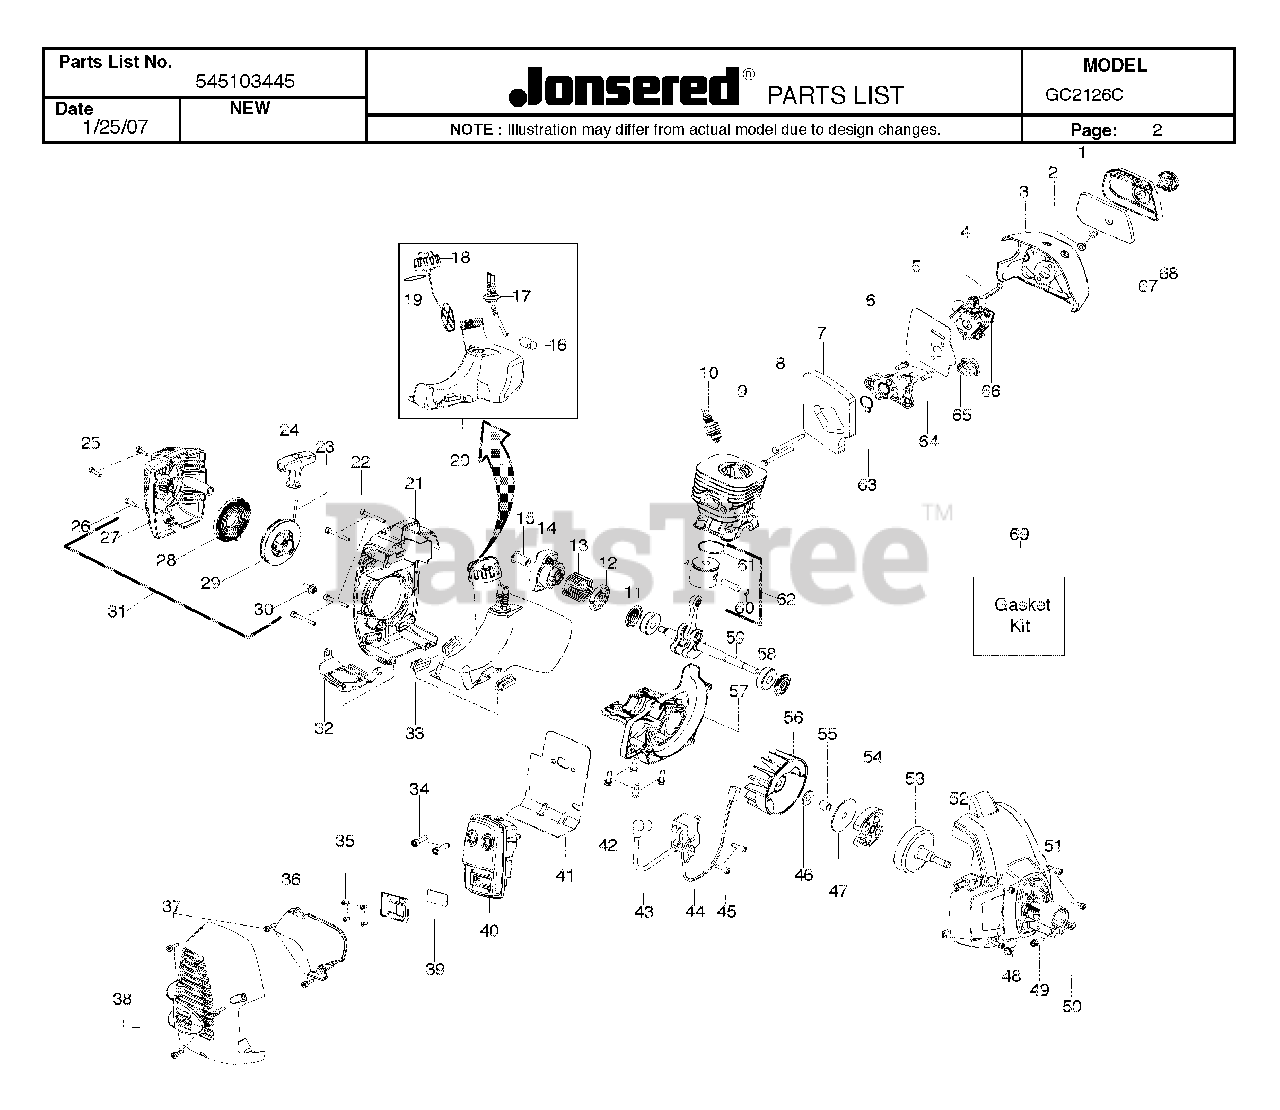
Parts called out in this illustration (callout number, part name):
1	FILTER AIRBOX
4	CHOKE LEVER
5	KIT GASKET CARB
6	CARB ADAPTOR
7	KIT GASKET 28CC TRIMMER
8	BOLT CARB ADAPTOR
9	CYLINDER
11	KIT SEAL CRANKSHAFT
12	WASHER STARTER
13	SPRING STARTER CUP
14	ASSY-STARTER CUP
15	COUPLING STARTER
16	FUEL PICK-UP ASSY
17	KIT FUEL LINE
18	ASSY - FUEL CAP W/RETAINER
19	O RING NITRILE
21	SHROUD REAR
25	SCREW M5-0.8X30MM
26	SCREW M4 X 1.75 PT 16MM
28	%KIT STARTER SPRING
29	KIT STARTER PULLEY
32	PLATE WEAR
33	ISOLATOR FUEL TANK
34	BOLT MUFFLER
35	SCREW-10-16 X 1/2 HI-LO
36	SHIELD HEAT
37	SCREW M4 X 1.75 PT 16MM
39	KIT SPARK ARRESTOR SCREEN
40	ASSY-MUFFLER
41	GASKET PAPER METAL
42	B0LT, C/SHAFT 36/41
43	IGNITION MODULE MBU-7
44	ASSY MODULE LEAD WIRE
45	SCREW M4 X .70 TT 16MM
47	WASHER-CLUTCH
50	LOCKNUT-HEX 10-24
51	SCREW M4 X .70 TT 16MM
53	ASSY-CLUTCH DRUM
54	%KIT CLUTCH ASSY
55	SPACER FLYWHEEL
57	CRANKCASE CASTING
58	BEARING RADIAL BALL (6201)
59	KIT CRANKSHAFT ASSY
60	WRIST PIN RET.
61	RING PISTON
62	KIT PISTON 28CC TRIMMER
63	KIT GASKET 28CC TRIMMER
64	B0LT, C/SHAFT 36/41
66	CARBURETOR
67	COVER AIR BOX
68	ASSY - AIR BOX KNOB
69	KIT GASKET 28CC TRIMMER
